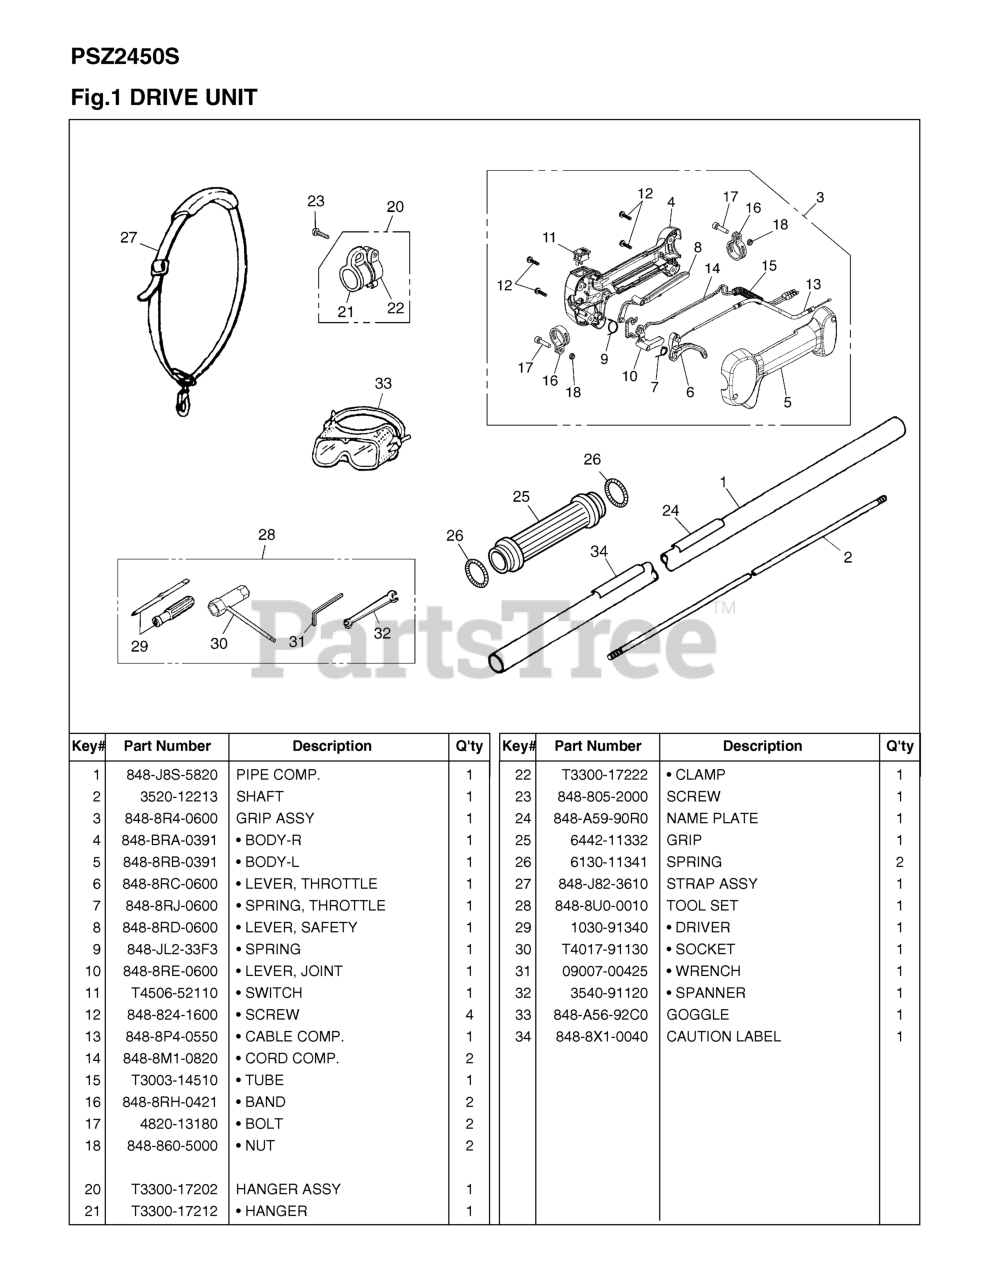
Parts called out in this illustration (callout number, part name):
1	PIPE COMP.
2	SHAFT
3	GRIP ASSY
6	LEVER, THROTTLE
7	SPRING, THROTTLE
8	LEVER, SAFETY
10	LEVER, JOINT
11	SWITCH
12	SCREW
13	CABLE COMP
14	CORD COMP
15	TUBE
17	BOLT (RPLS 2850-14220)
20	HANGER ASSY
23	SCREW
24	NAME PLATE
25	GRIP
26	SPRING
27	STRAP ASSY
28	TOOL-SET
29	DRIVER
32	SPANNER
33	GOGGLE
34	LABEL, CAUTION
